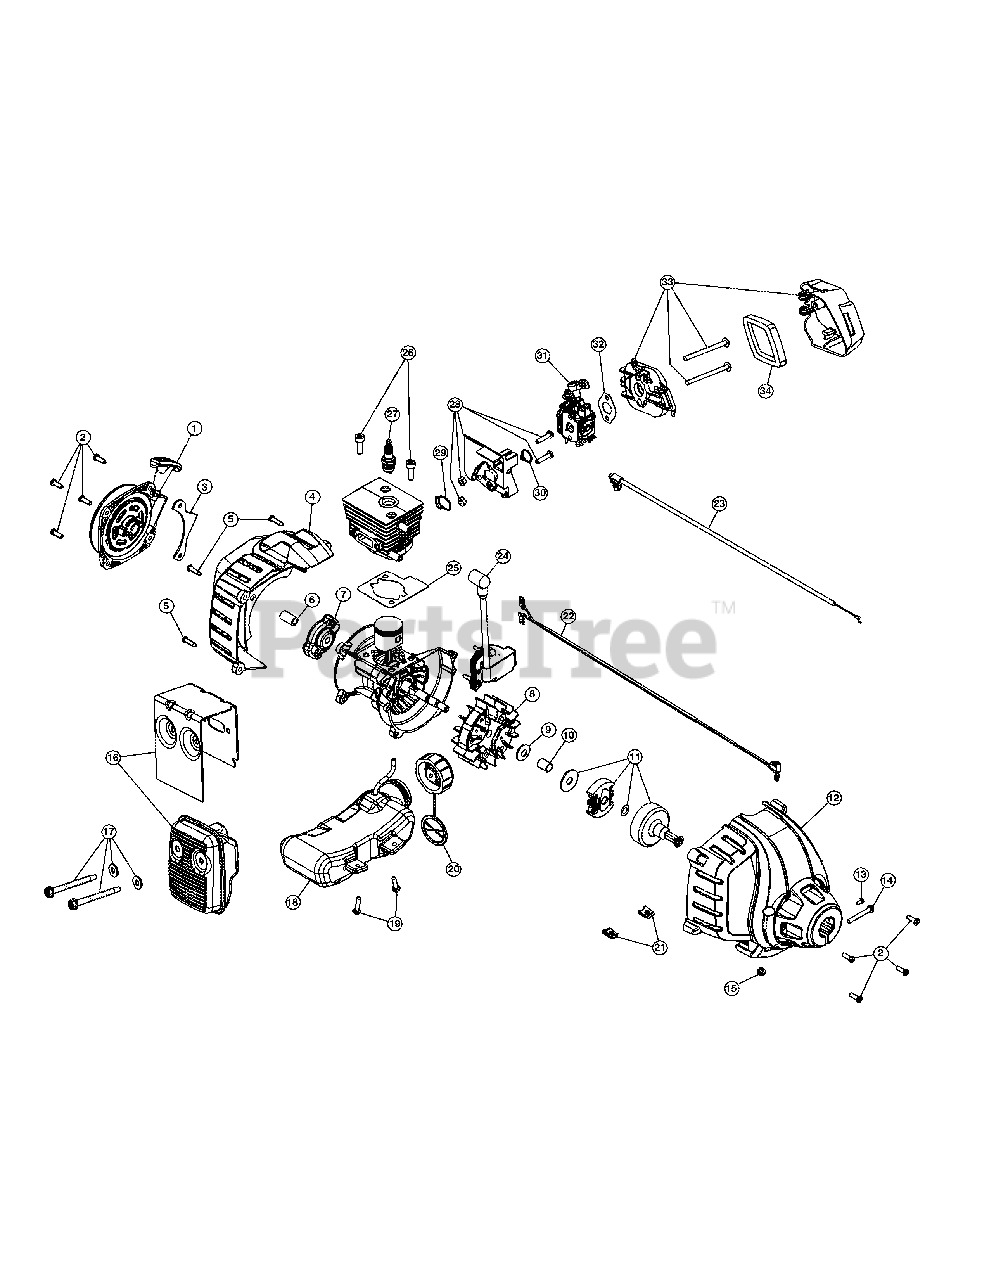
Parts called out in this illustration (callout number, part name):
1	Rear Cover Assembly (Incl. 2 & 3)
2	Starter Screw
3	Starter Assembly Guard (Incl. 2)
4	Rear Engine Cover (Incl. 5)
5	Cover Screw
7	Pawl Assembly
8	Flywheel Assembly
11	Clutch Assembly
12	Clutch Cover Assembly
13	Anti-Rotation Screw
14	Clamp Screw
15	Clamp Nut
16	Muffler Assembly (Incl. 17)
17	Muffler Screw
18	Fuel Tank Assembly (Incl. 19 & 20)
21	U-Shaped Nut
22	Lead Wires
23	Throttle Cable
24	Module Assembly
25	Cylinder Gasket
26	Cylinder Bolt
27	Spark Plug
28	Insulator Assembly (Incl. 29 & 30)
29	Insulator O-Ring
30	Carburetor O-Ring
31	Carburetor
32	Carburetor Gasket
33	Aircleaner Assembly (Incl. 34)
34	Aircleaner Filter
